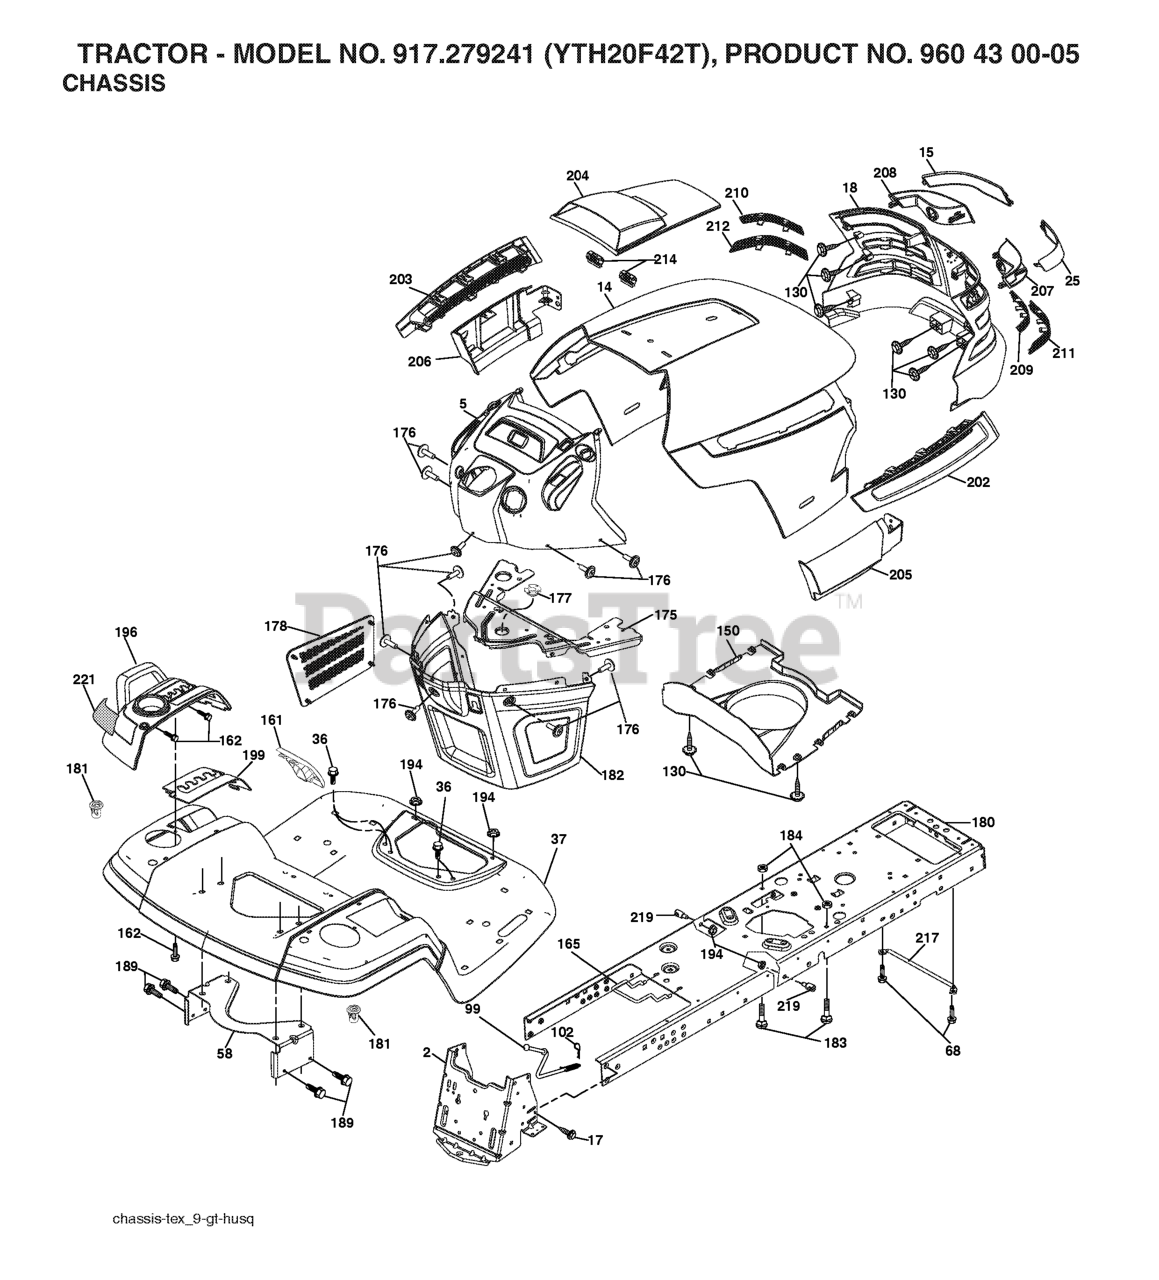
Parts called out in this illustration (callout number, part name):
2	DRAWBAR.TGB/TGW
5	DASH.HUSQ.UPR.ELE.SVMD
14	HOOD.PNT.HUSQVARNA.GT.
15	LENS.LH.TEX.GT.HUSQ.CL
17	SCREW 3/8-16X3/4
18	GRILLE.ASM.TX.GT.HUSQ
25	LENS.RH.TEX.GT.HUSQ.CL
36	SCREW 5/16"
37	FENDER.PNT.TX.GT.CH/FW.ORANGE
58	BRKT.SUPPORT.FNDR/TANK
68	Screw 5/16-18 x 1/2 Hex, Self Tapping 5/16-18 x 1/2
99	ROD.BYPASS.K46.TG
102	RETAINER M
130	SCREW
150	AIR.DUCT.TEXGT.HUSQ.SV
161	CONSOLE.FUEL.WINDOW.HU
162	SCREW.HI-LO.CONSOLE
165	SUPPORT.TANK.REAR.B/TE
175	PLATE.CROSSMEMBER.HUSQ
176	SCREW.#10-24X5/8.RN.QU
177	BUSHING, STEERING
178	CARGO.ASM.NET.TXGT.W/C
180	CHASSIS.STAMPING.LT/GT
181	BUSHING.MNT.FEND.CRGO.
182	DASH.LOWER.COMMON.12V.
183	BOLT.5/16-18X1-1/4 FULL.THREAD
184	SPACER.FENDER
194	NUT LOCK HEX FLANGE 5/16-18
195	PLUG.HOLE.DASH.LOWER.12V.BLK
196	RP CONSOLE.ASM.DECKLFT.W/
199	PLATE.DECK.LIFT.HUSQVARNA.GT
202	VENT.SIDE.HOOD.HUSQ.RH.GREY
203	VENT.SIDE.HOOD.HUSQ.LH.GRAY
204	VENT.TOP.HOOD.HUSQVARN
205	SKIRT.HOOD.SIDE.HUSQ.RH.GREY
206	SKIRT.HOOD.SIDE.HUSQ.LH.GREY
207	BEZEL.RH.TEX.GT.HUSQ
208	BEZEL.LH.TEX.GT.HUSQ
209	INSERT.HEX.GRILL.HUSQ.GREY
210	INSERT.HEX.GRILL.HUSQ.
211	INSERT.HEX.GRILL.HUSQ.
212	INSERT.HEX.GRILL.HUSQ.
214	CLIP.RETAINER.TINNER.
217	ROD PIVOT CHASSIS/HOOD
219	STUD.FASTNER.W/ANTI-ROTATE
221	REFLECTOR.LH.TEX GT HU
